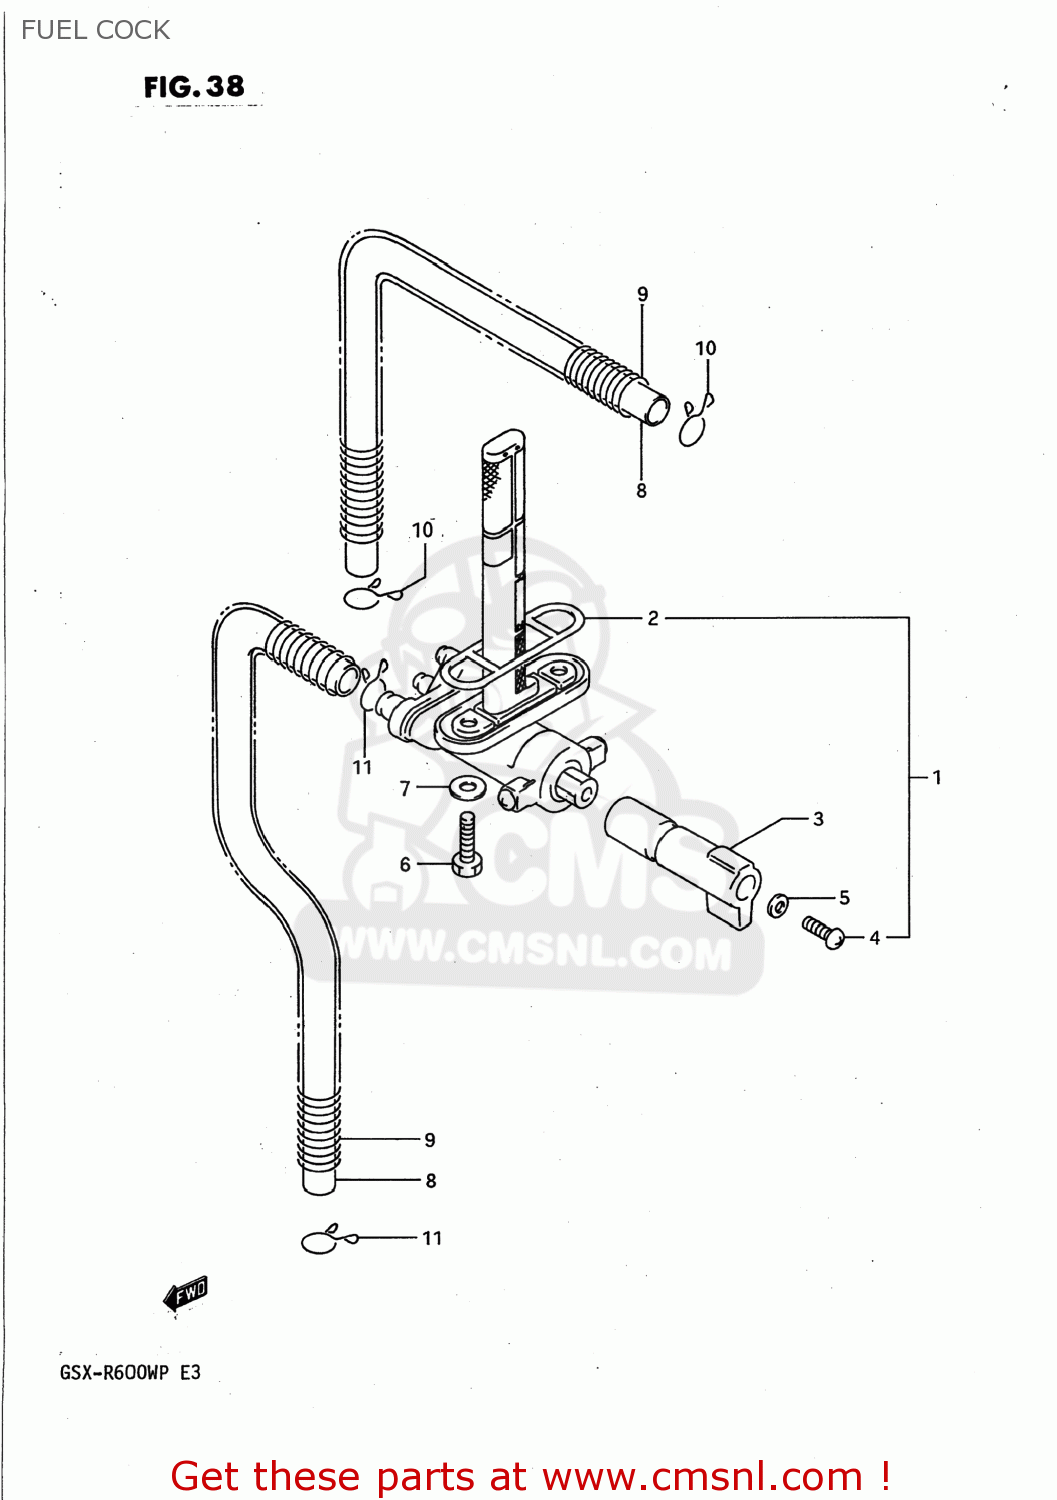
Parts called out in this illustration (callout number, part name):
1	COCK ASSEMBLY,FUEL
2	O RING,FUEL TANK JOINT
3	LEVER,FUEL COCK
4	SCREW
5	LOCK WASHER
6	BOLT(6X20)
7	GASKET(6.4X11.5X0.8) (NAS)
8	HOSE
9	SPRING
10	CLIP
11	CLIP
